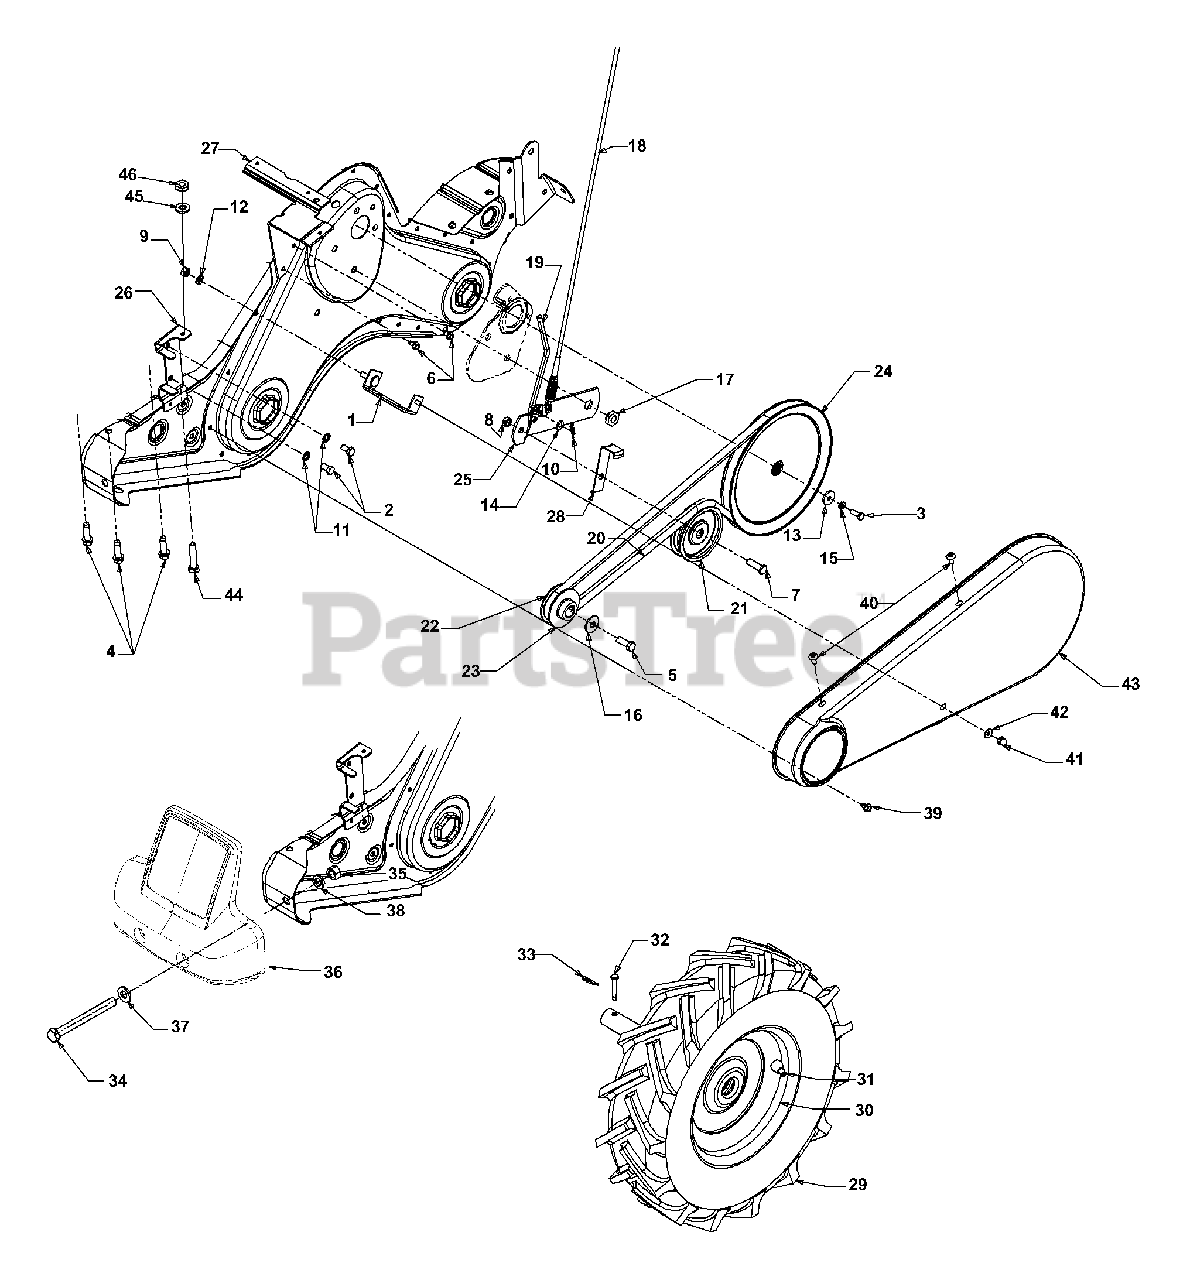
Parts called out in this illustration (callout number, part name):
1	Belt Cover Brkt. Ass'y
2	Hex Bolt 5/16-24 x.62" Lg.
3	Hex Bolt 1/4-28 x.75" Lg.
4	Hex Wash.TT-Sems Screw 3/8-16 x 1.250" Lg.
5	Hex Bolt 3/8-24 x 1.00
6	Hex Wash. Hd. S-Tap Scr.
7	Hex Cap Screw 3/8-16 x 1.25
8	Ctr. Lock Jam Nut 3/8-16
9	Hex Nut 5/16-18
10	Internal Cotter Pin
11	Hairpin Clip
12	L-Wash. 5/16" I.D.
13	Fl-Wash. 1/4 I.D. x.93 O.D.
14	Spring-Wash.317 x.625 O.D. x.099
15	L-Wash. 1/4" I.D.
16	Bell-Wash.396 x 1.140 x.095
17	Shld. Nut 7/16-20
18	Clutch Cable
19	Idler Pulley Rod
20	Belt: 4L x 58.16 Lg.
21	Fl-Idler w/Flange 3.75" O.D.
22	Outer Engine Pulley Half
23	Inner Engine Pulley Half
24	Input Pulley
25	Idler Bracket
26	Belt Keeper Brkt.
27	Shift Cover Brkt.
28	Idler Belt Keeper
29	RH Wheel Ass'y Comp. 16.0 x 4.0
29	LH WheelAss'yy Comp. 16.0 x 4.0
29	Tire Only 16.0 x 4.0
32	Clevis Pin
33	Internal Cotter Pin
34	Hex Hd. Cap Screw 1/2-13 Gr. 5
35	Hex Nut 1/2-13 Thd. Gr. 5
36	Counterweight
37	Fl-Wash, 1/2 x 1.25 x.10
38	L-Wash. 1/2" Lg.
39	Hex Screw 1/4-20 x.375" Lg.
40	Screw 1/4-14 x.625" Lg.
41	Acorn Lock Nut
42	Fl-Washer.271 x.630 x.065
44	Hex Bolt 5/16-18 x 1.50" Lg.
45	Bell-Wash.340 I.D. x.872 O.D.
46	Hex Nut 5/16-18
